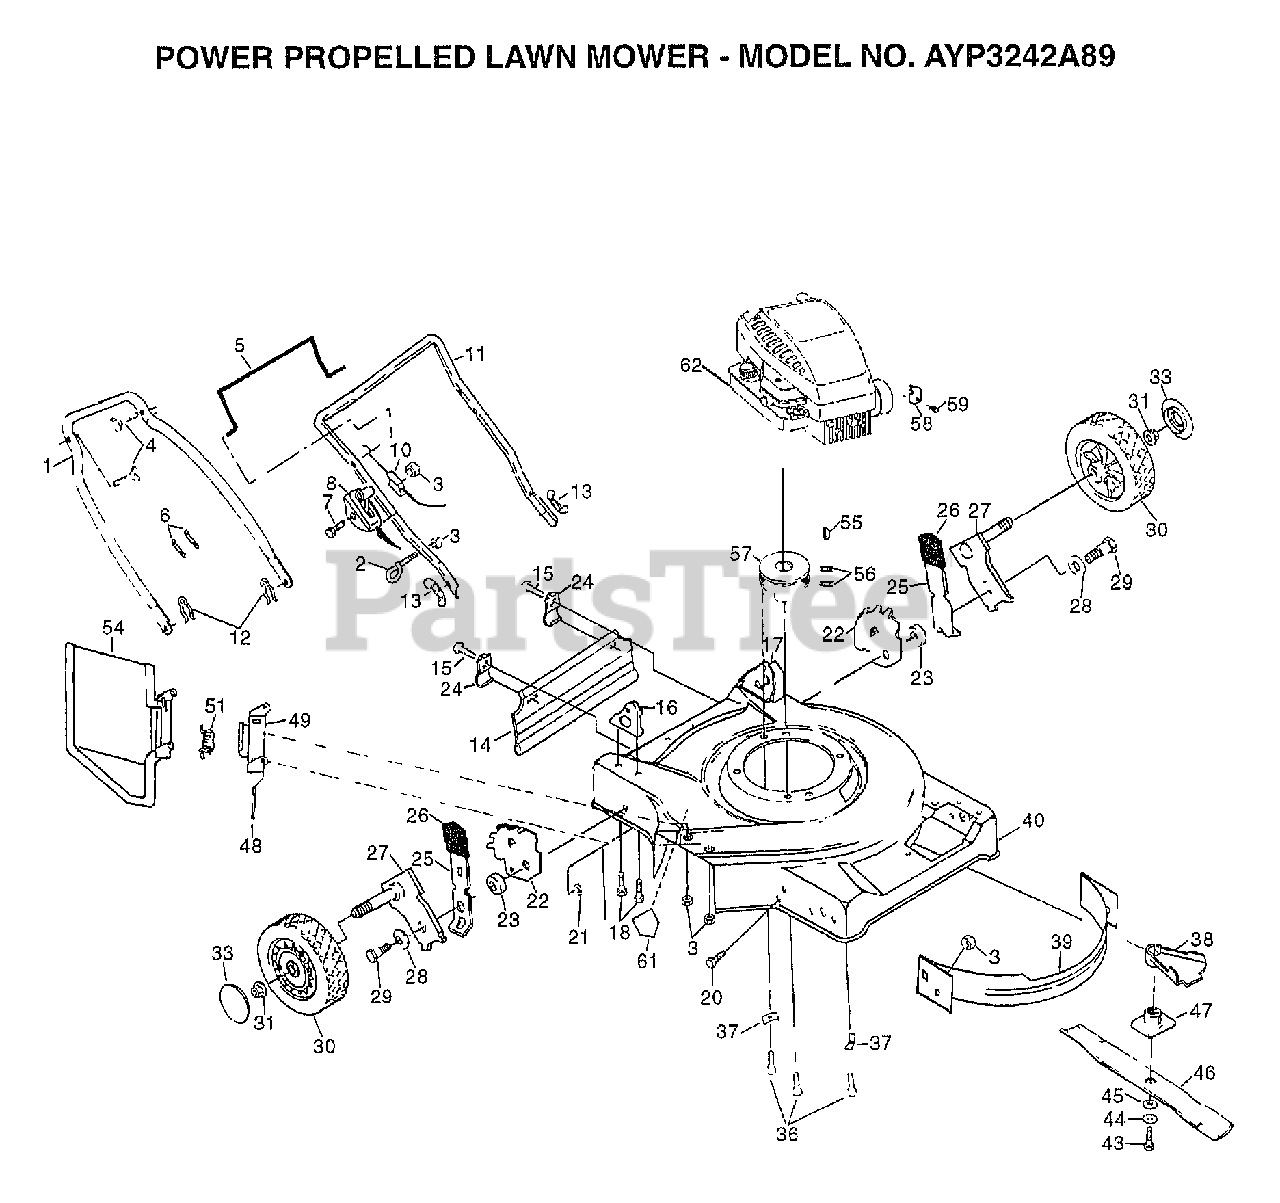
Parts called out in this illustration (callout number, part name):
1	HANDLE LOWER
2	ROPE GUIDE
4	BOLT.HANDLE.LM
5	BAIL.CNTRL.STD.BL
7	SCREW.HXHD.WASH.
8	CONTROL.THL.49.35
10	"CABLE,ENG ZONE CO"
12	HAIRPIN COTTER
13	"NUT,WING PM"
14	SKIRT.REAR.FGD.22
15	TAPPING SCREW
16	HDLE BRKT ASSY.RH
17	HDLE BRKT ASSY LH
18	SCREW 5/16-18X3/4
20	SCREW
21	LOCKNUT PM
22	BRACKET.ADJ.9POS.
23	SPACER.HEIGHT.ADJ
24	"BRKT,DEFL PM"
25	SPRING SELECTOR
26	KNOB PM
27	ARM.AXLE.ASM.BZP.
28	"WASHER, BELLEVIL."
29	BOLT SHLD 3/8-16
30	WHEEL.8X2.PR.RAD.
31	HEX FLANGE LOCKNT
33	HUB CAP
36	BOLT.ENG.3/8-16
39	BAFFLE FRONT 22SD
40	MOWER HSG KIT
43	SCREW
44	LOCKWASHER
45	"WASHER,HARDEN"
46	"BLADE.MULCH.22"""
47	ADAPTOR.BLADE.LM
48	ROD.HINGE.COMBI-C
49	BRACKET.HINGE.W/F
51	"SPRING,TORSION"
55	HI PRO KEY PM
56	SCREW
57	ENGINE.PULLEY.FWG
58	CABLE CLAMP
59	SCREW PM
61	DECAL-DANGER PM
